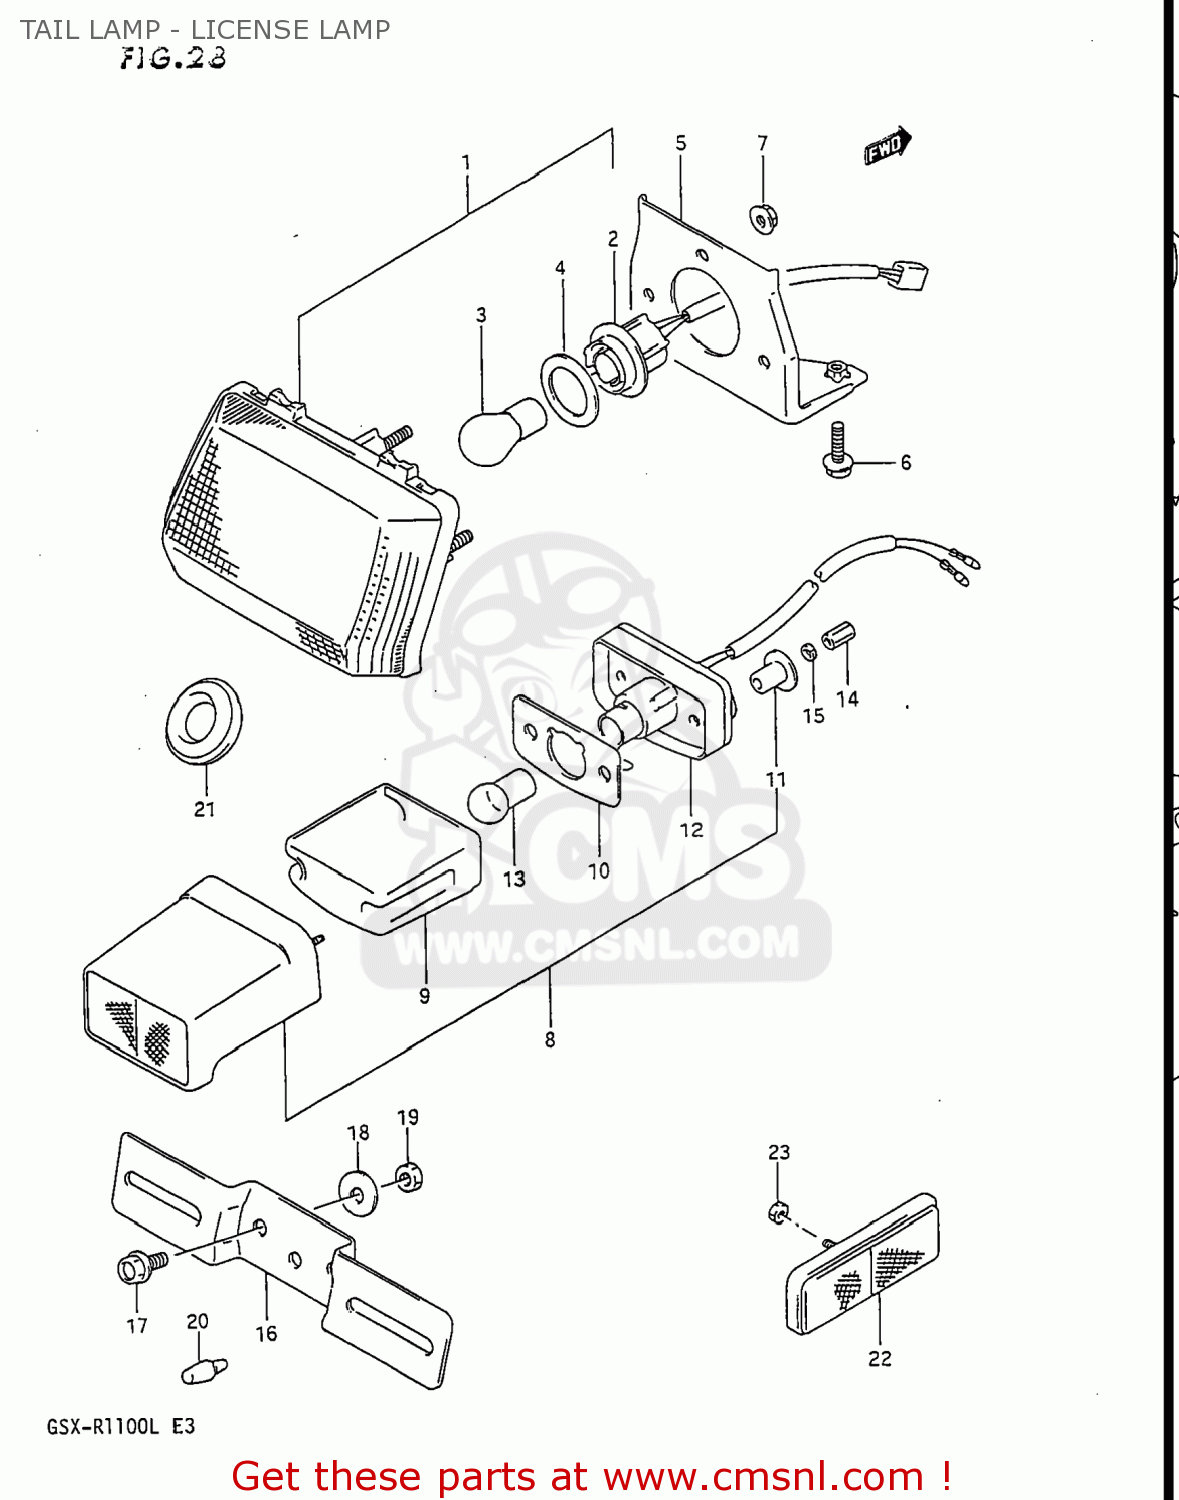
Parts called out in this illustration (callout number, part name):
1	LAMP ASSEMBLY,REAR COMBINATION
2	SOCKET
3	BULB(12V21/5W,BF141-49642A)
4	CUSHION,RUBBER
5	BRACKET COMP,REAR COMBINATION LAMP
6	BOLT
7	NUT
8	LAMP ASSEMBLY,LICENSE
9	LENS
10	GASKET,LICENSE LAMP (NAS)
11	SPACER
12	HOUSING,LICENSE
13	BULB
14	NUT
15	LOCK WASHER
16	BRACKET,LICENSE PLATE
17	BOLT
18	WASHER
19	NUT
20	CUSHION
21	CAP OD:40
22	REFLECTOR ASSEMBLY,REAR
23	NUT 5MM
